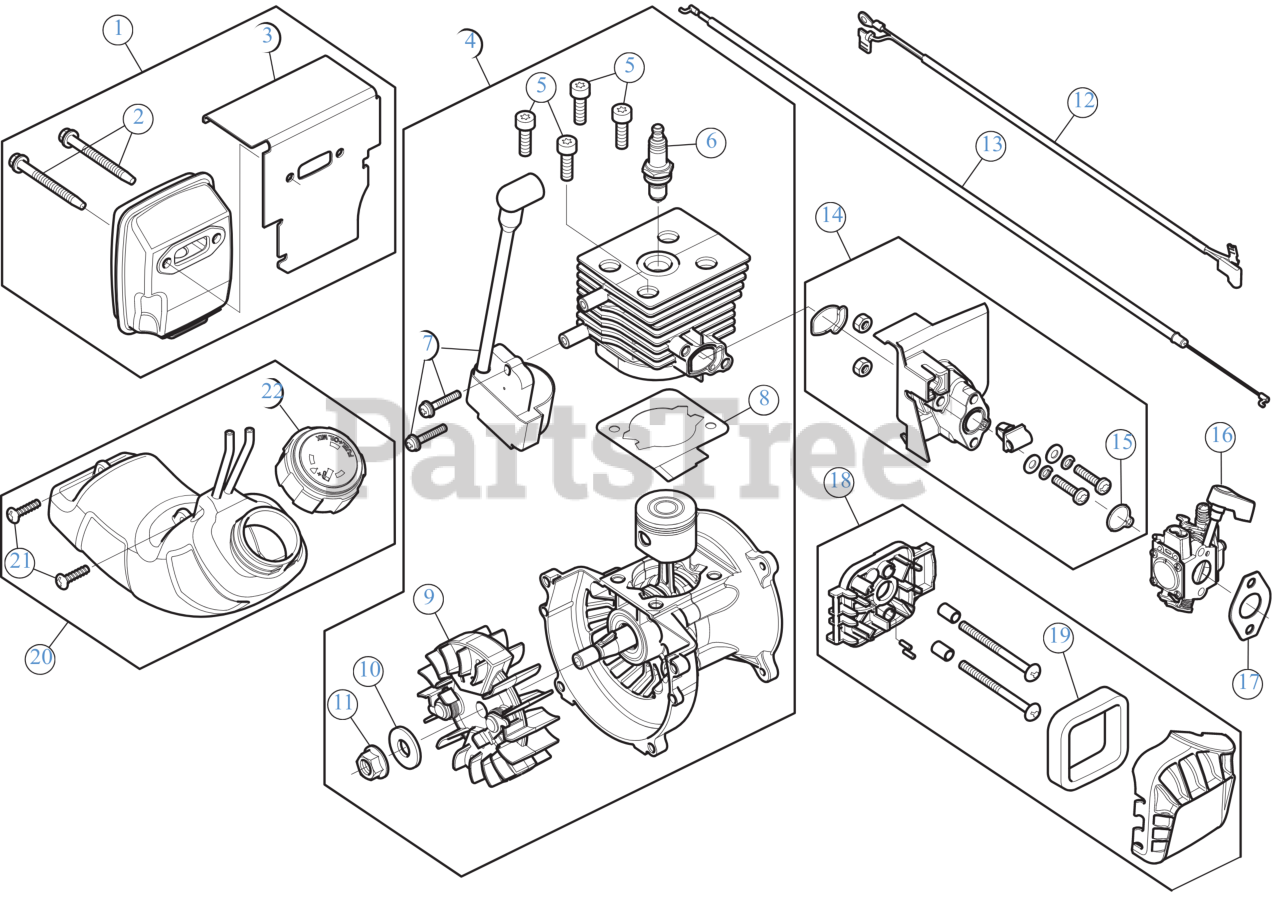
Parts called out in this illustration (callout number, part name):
1	MUFFLER ASSEMBLY 27CC
2	MUFFLER SCREW
3	MUFFLER GASKET
4	SHORT BLOCK
5	SCREW 1/4 x 20 x .8125
6	SPARK PLUG
7	MODULE ASSEMBLY
8	GASKET CYL
9	FLYWHEEL ASSEMBLY
10	WASHER .406X1.0X.095
11	NUT 3/8-24
13	THROTTLE CABLE
14	INTAKE ASSEMBLY
16	CARBURETOR ASSEMBLY
17	GASKET CARB
18	AIRCLEANER ASSEMBLY
20	FUEL TANK ASSEMBLY
21	SCREW 8-16 x 3/4
